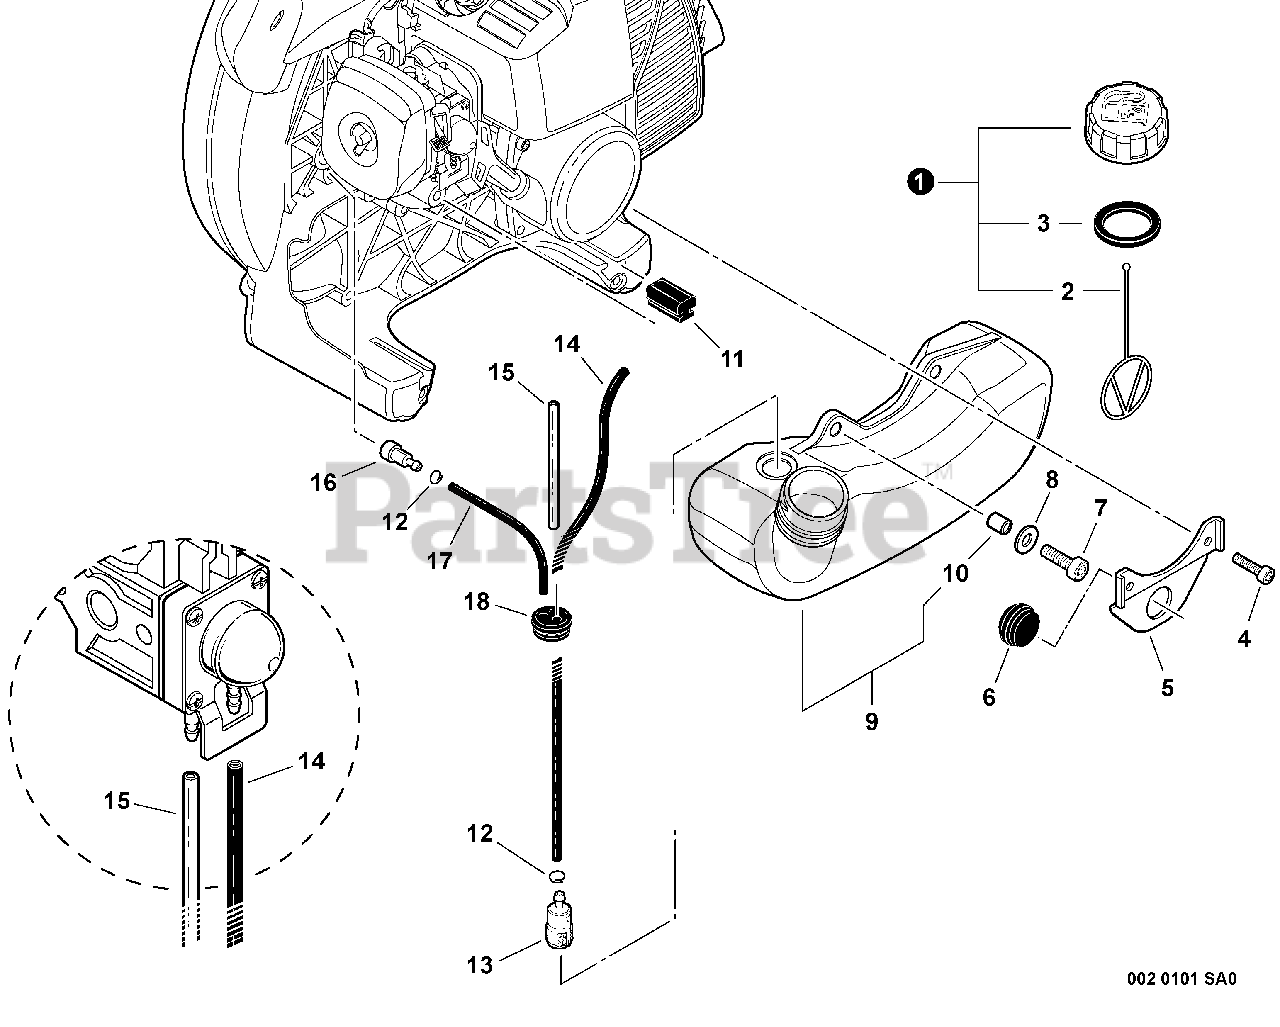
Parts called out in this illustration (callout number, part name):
1	CAP ASSY, FUEL
2	CONNECTOR, CAP L= 100 MM
3	GASKET, FUEL CAP
4	BOLT, TORX 4×16
5	BRACKET, FUEL TANK
6	CUSHION
7	BOLT, TORX 5×16
8	WASHER 5.5×12×0.8
9	TANK ASSY, FUEL
10	SPACER 6.2×7.8×6
12	CLIP 6 MM
13	FILTER, FUEL
14	PIPE, FUEL 3×5×210 BLACK
15	PIPE, FUEL 3×6×85 CLEAR
16	VENT ASSY
17	PIPE, FUEL 3×5×80 BLACK
18	GROMMET, FUEL
